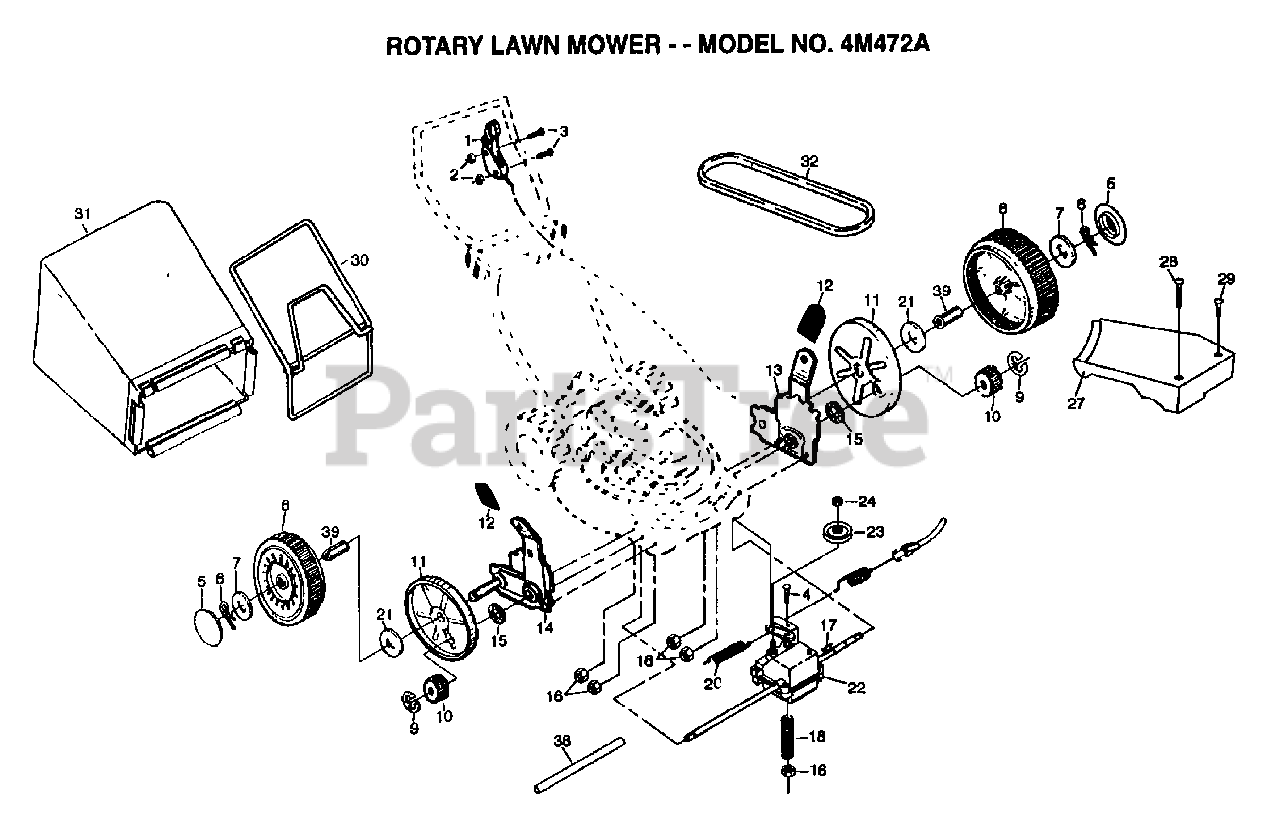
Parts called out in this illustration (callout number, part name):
1	CONTROL.DRIVE
2	LOCKNUT
3	SCREW
4	BOLT.1/4-20X2.0
5	HUB CAP
6	RETAINER CLIP PM
7	WASHER
8	WHEEL.8X2.LP.PR
9	E-RING.7/16.RE.
10	PINION.GEAR
11	DUST SHROUD PM
12	KNOB PM
15	WASHER PM
17	HI PRO KEY
18	SPRING.TENSION
20	SPRING
21	WASHER FLUT
23	PULLEY.DRIVEN
24	LOCKNUT
27	"COVER.DRIVE 22""RD"
30	CATCHER FRAME
31	GRASS BAG
38	DRV SHAFT TUBE PM
39	BUSHING.HEX
